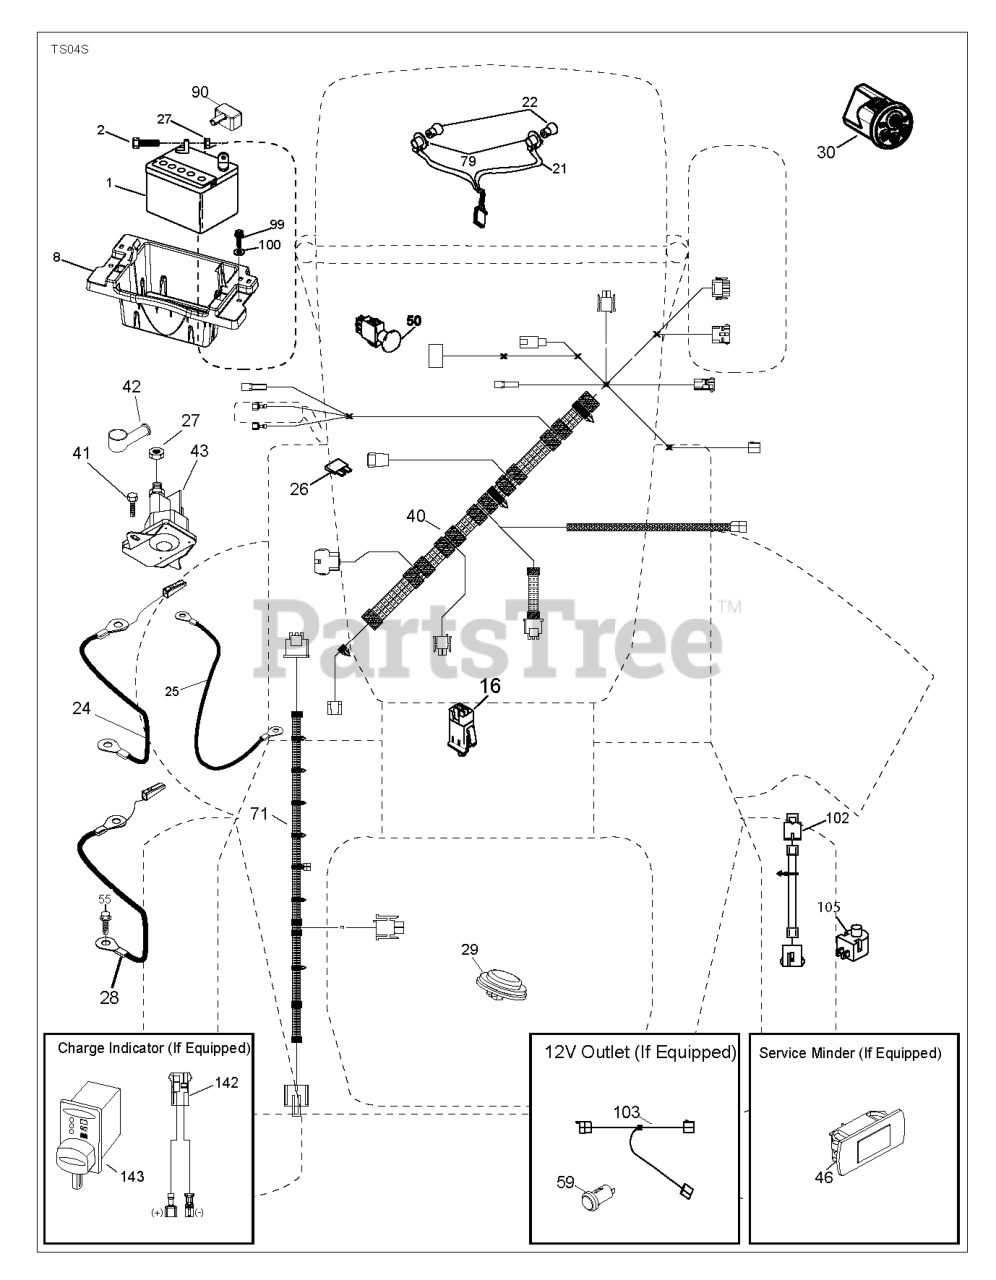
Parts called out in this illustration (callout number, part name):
1	Battery 12 Volt 25 Amp
2	BOLT.HEX.1/4.X.3/4.DICHROMATE
8	TRAY.BATTERY BOX.FRONT
16	SWITCH INTERLOOK PUSH-IN
21	HARNESS.LIGHT W/4152J BULBS
24	CABLE.BTRY.HARN.POS.LEAD
25	CABLE.STARTER.8GA.17.5
26	FUSE 20AMP
27	NUT
28	CABLE.GROUND.STARTER
29	SWITCH.SEAT.OPC.GRY.BUTTON/CAP
30	SWITCH.ASM.SMARTSWITCH.MY15.TR
40	HARNESS.DASH.EL.SIS.RECT.FBAT
41	SCREW
42	TERMINAL COVER
43	SOLENOID.W/BRASS.PLUNGER
46	GUAGE.SRVCMNDR.HRMTR.
50	RP.PTO.SWITCH.8 TERMINAL.BLACK
55	SCREW 5/16"
71	HARNESS.CHAS.TEX.SIS.FBAT.TWIN
79	BULB HOLDER ASM.
90	COVER.TERMINAL.BATTERY
99	SCREW HEXWSHR 1/4-20X3/4
100	WASHER
102	REVERSE SWITCH
105	HARNESS PIGTAIL PCH TEX ROS
